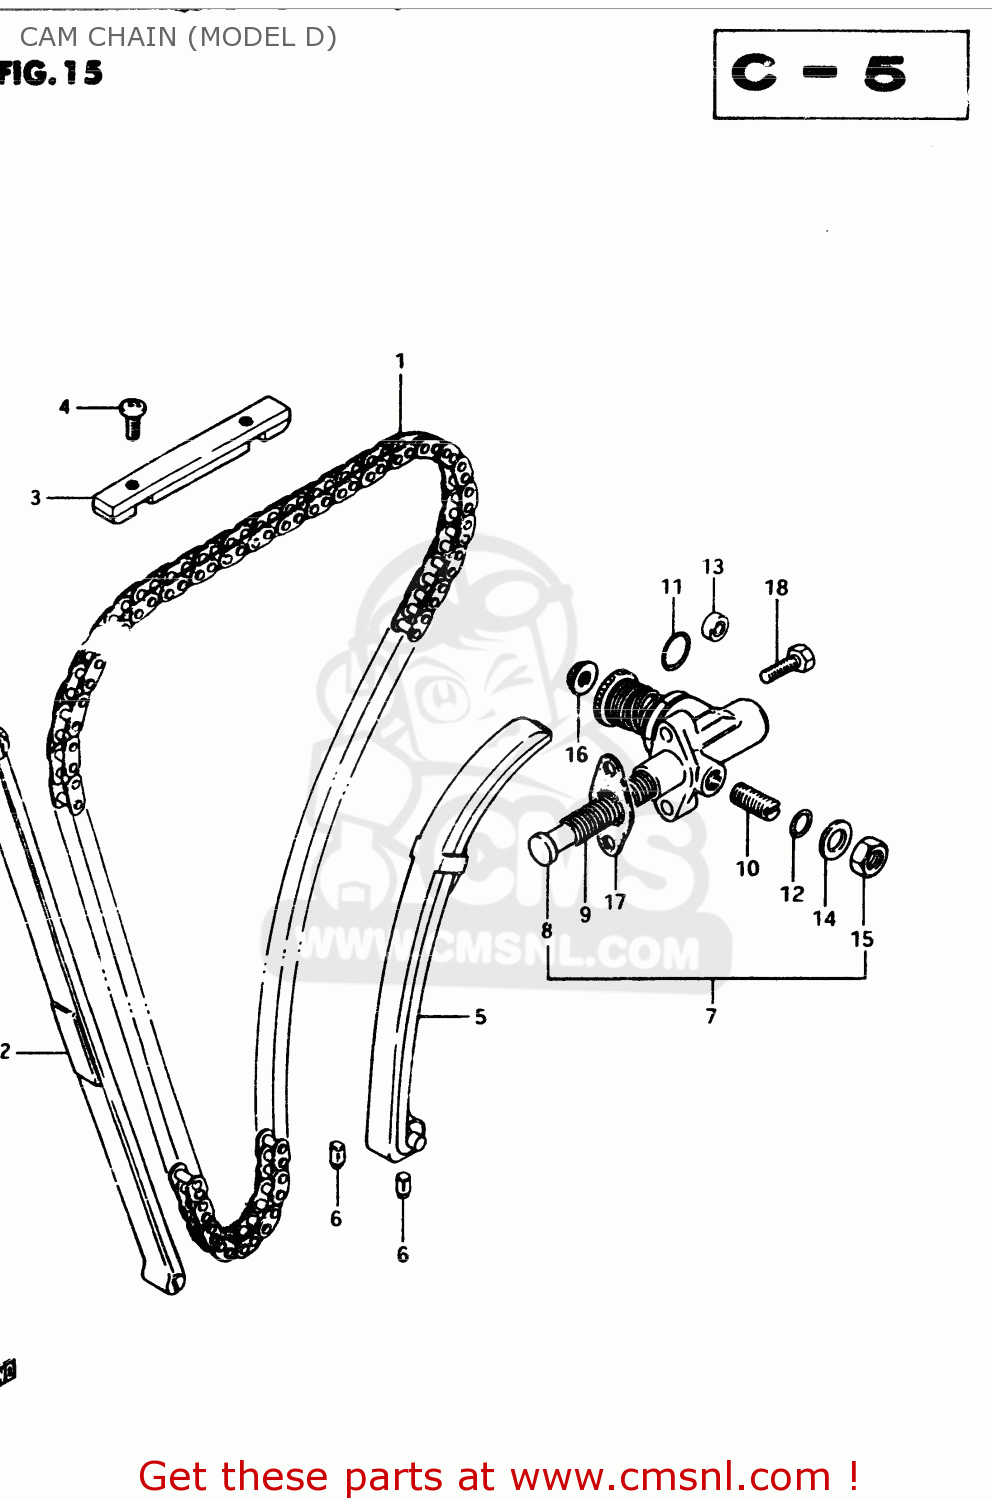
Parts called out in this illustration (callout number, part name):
1	CHAIN,CAMSHAFT DRIVE
2	GUIDE,CAM CHAIN NO.1
3	GUIDE,CAM CHAIN NO.3
4	SCREW
5	TENSIONER,CAM CHAIN
6	CUSHION,CAM CHAIN TENSIONER
7	ADJUSTER ASSEMBLY,TENSIONER
8	ROD,PUSH
9	SPRING
10	SCREW,TENSIONER ADJUST
11	O RING(D:2.4,ID:20.8)
12	O RING(D:1.9,ID:5.7)
13	SEAL,OIL(10X16X4)
14	WASHER,8.5X16X
15	NUT
16	NUT
17	GASKET,TENSIONER ADJUSTER (MCA)
18	SCREW
